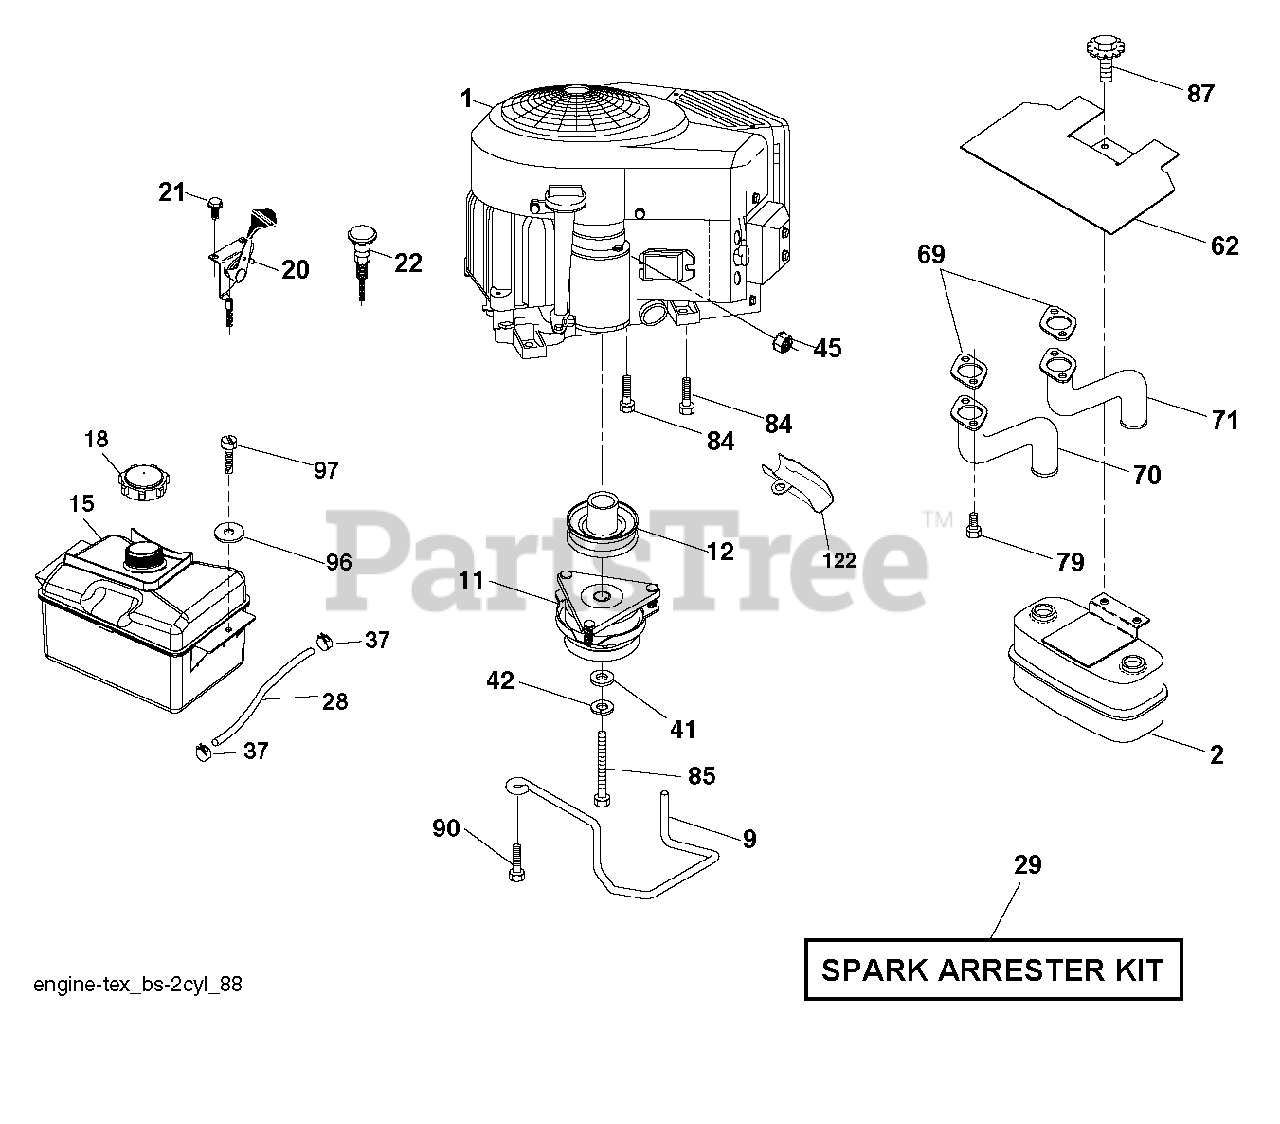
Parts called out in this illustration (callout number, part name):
2	MUFFLER.TWIN.CYL.LOW.TONE
9	KEEPER.BELT.ENGINE.4.2
11	CLUTCH.ELECTRIC.LT.48"*
12	PULLEY.ENGINE.TUFFTORQ
15	TANK.ASM.FRNT.2.GA.DAPCO.E10
18	CAP ASM.FUEL.2.25"FR.
20	THROTTLE CABLE
21	SCREW.#10 X 0.750.BOS THREAD
22	CONTROL CHOKE
28	LINE.FUEL.20
29	ARRESTER SPARK (OPTIONAL)
37	HOSE CLAMP
42	LOCKWASHER
45	NUT
62	SHIELD.HEAT.MUFFLER
69	GASKET.MUFFLER
70	TUBE MANIFOLD LH
71	EXHAUST TUBE RH
79	SCREW.SOCKET.HEAD.5/16-18
84	SCREW.3/8-16
85	BOLT HEX 7/16-20X4-1/4"
87	BOLT, 5/16-18 X 1 3/4
90	SCREW 3/8-16X1
97	SCREW HEXWSHR 1/4-20X3/4
122	EXTENSION DRAIN OIL
